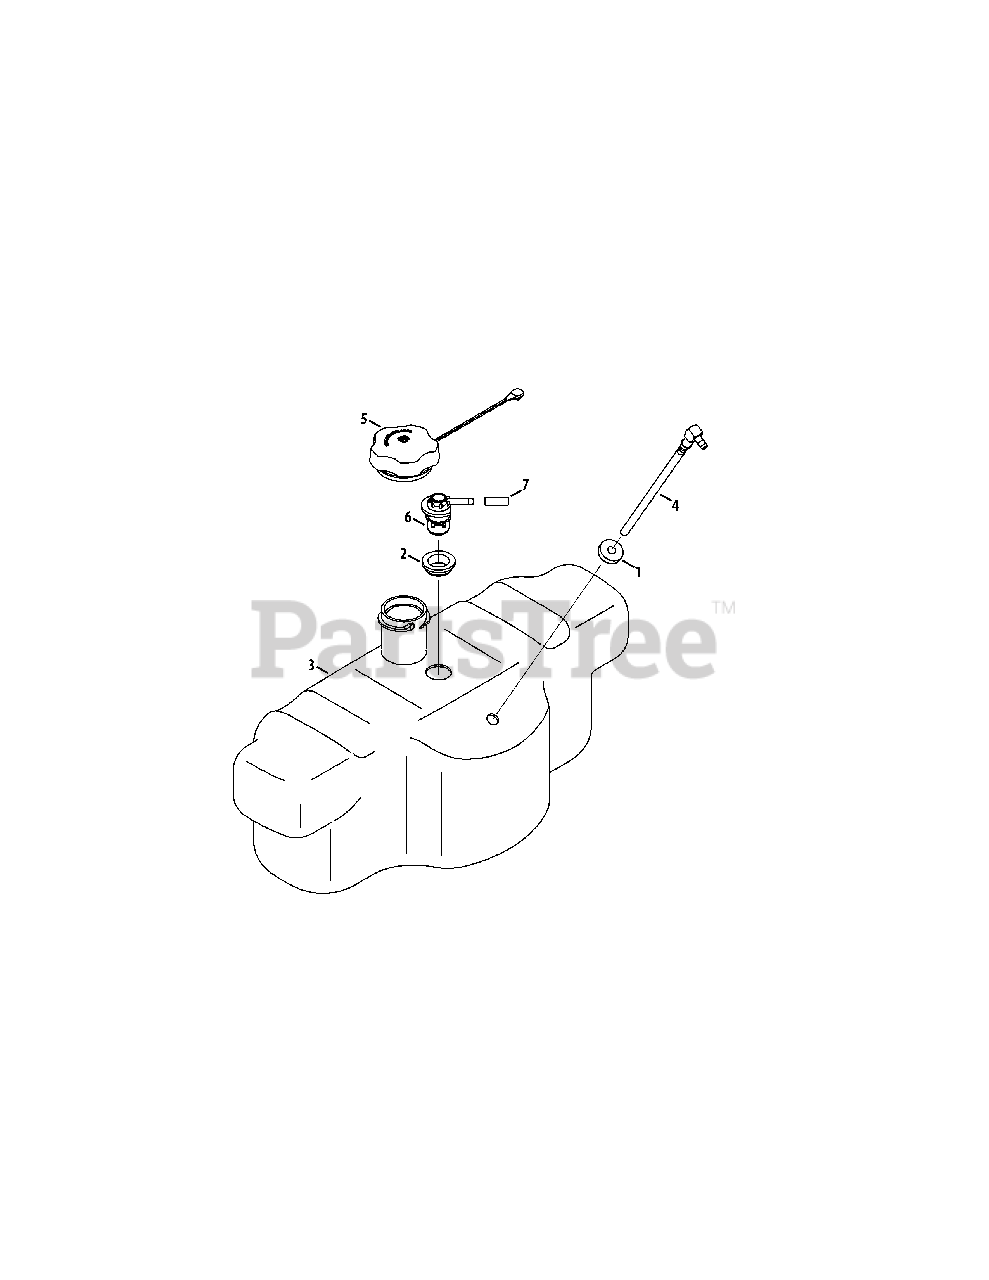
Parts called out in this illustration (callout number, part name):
1	Fuel Tank Bushing
2	Rubber Grommet
3	Fuel Tank, 2.82 Gallon
4	Fuel Pick-Up Fitting
5	Fuel Cap
6	Fuel Rollover Valve
